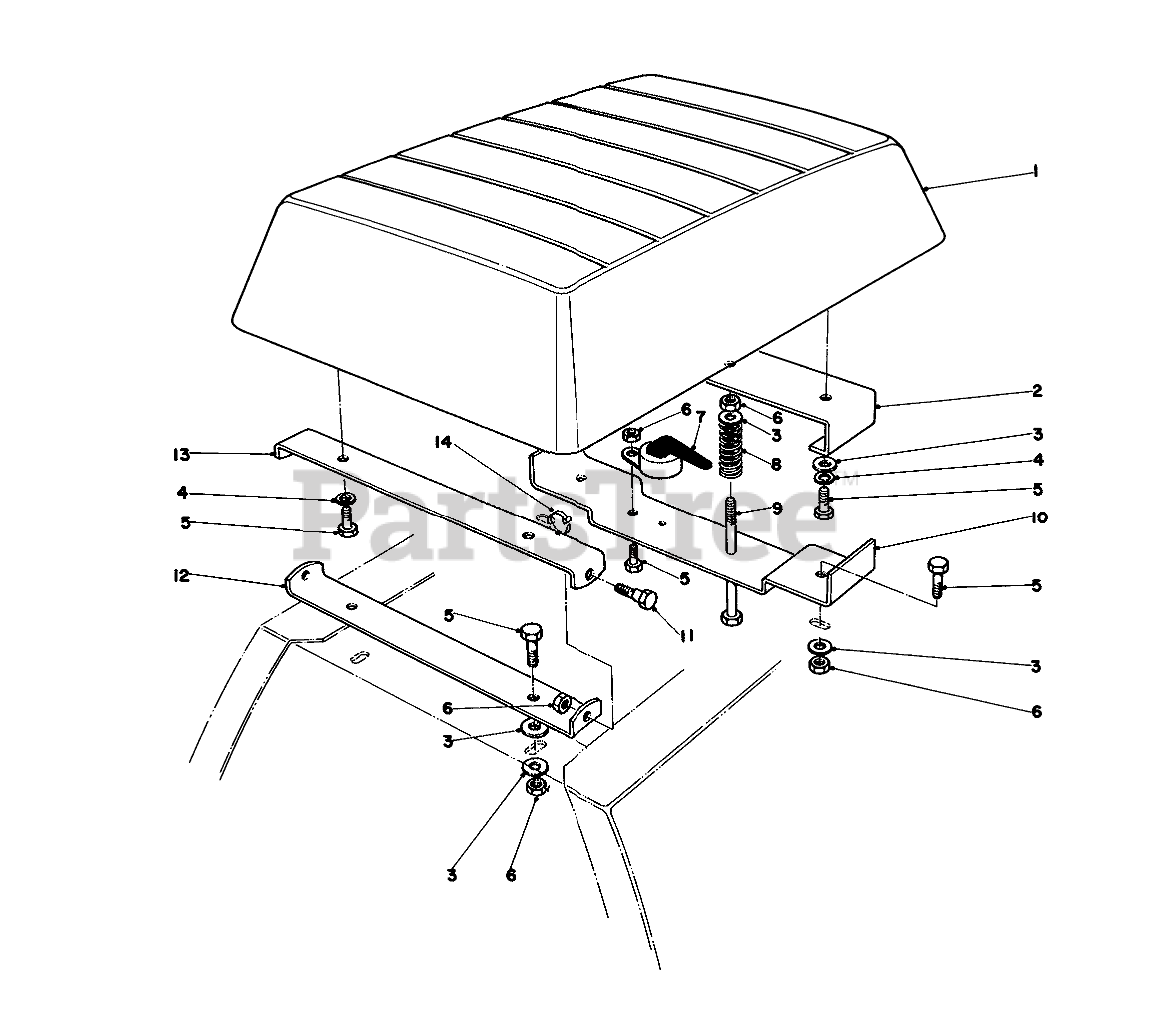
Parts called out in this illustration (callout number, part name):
2	Rear Support Seat
3	WASHER-FLAT
4	WASHER-LOCK
5	SCREW-HH
6	NUT-LOCK, CONE
7	SEAT SWITCH
8	Spring
9	SCREW-HH
10	Seat Support-Rear Lower
11	SCREW-SHOULDER
12	Seat Pivot Brkt-Lower
13	Seat Pivot Brkt-Upper
14	TIE-CABLE
